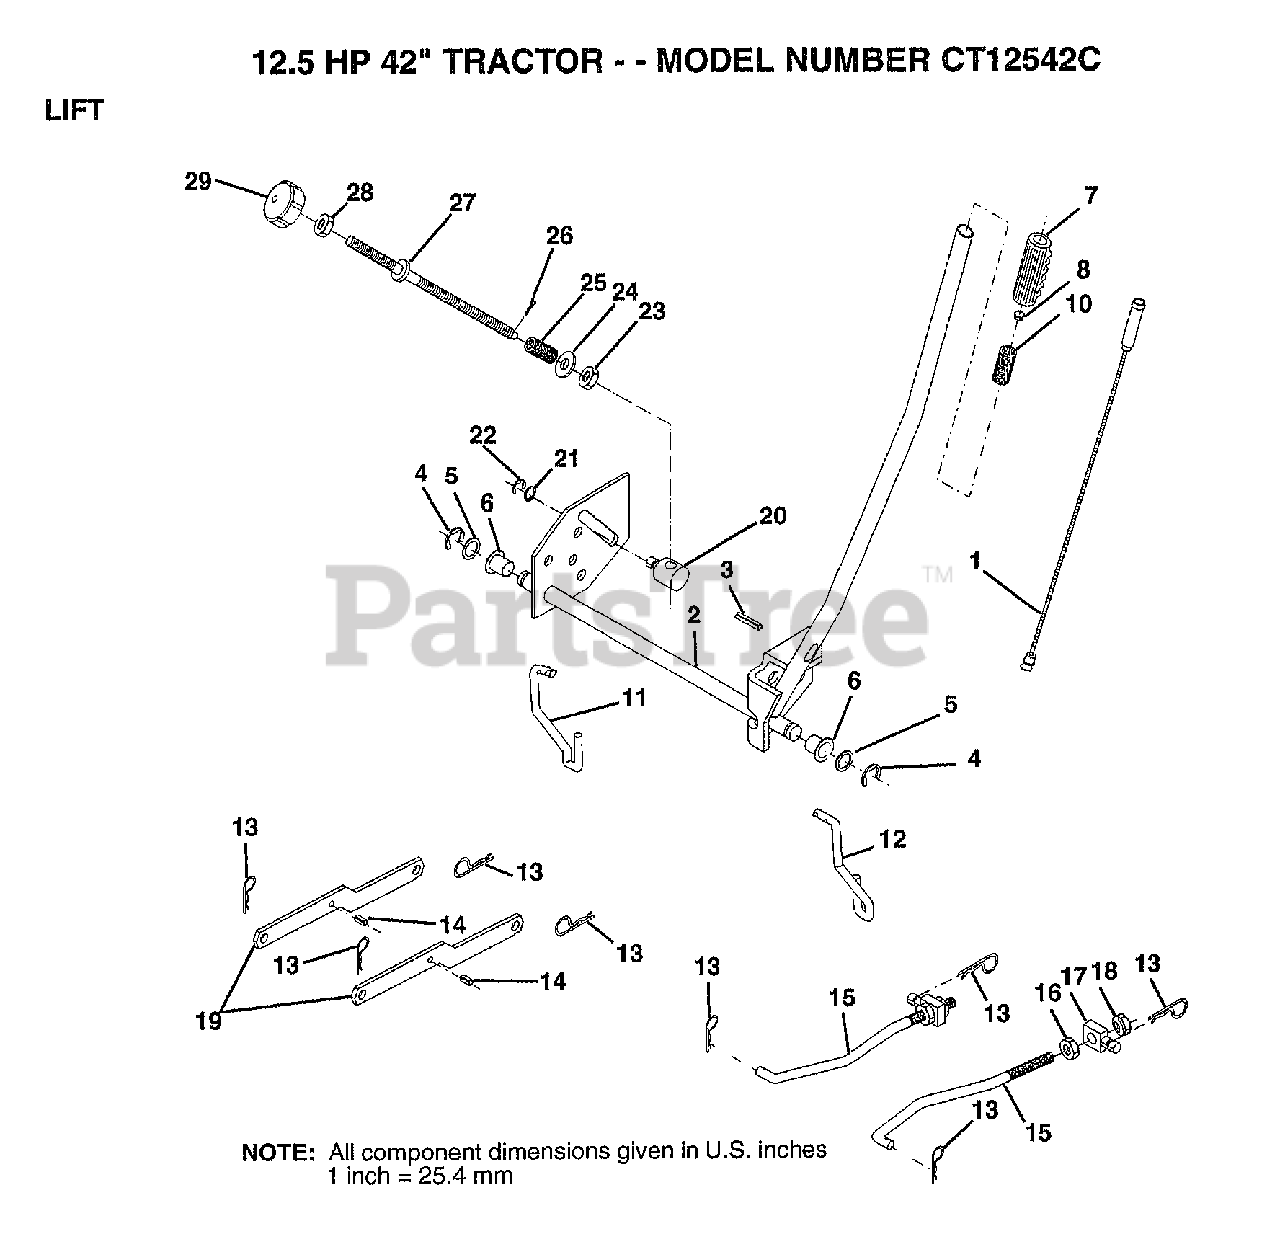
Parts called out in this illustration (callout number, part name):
1	WIRE ASM
3	PIN-GROOVE LT
5	WASHER
6	NYLON BEARING
7	GRIP
11	LINK LIFT LH
12	LIFT LINK RH
14	"PIN,SPRING"
15	LINK.FRONT
16	NUT
17	TRUNION
18	NUT.LK.W/WSH.1/2.
20	TRUNION LT
21	WASHER
22	KLIP RING
23	NUT T
24	WASHER
25	SPRING T
28	NUT
29	KNOB INF 3/8-16
